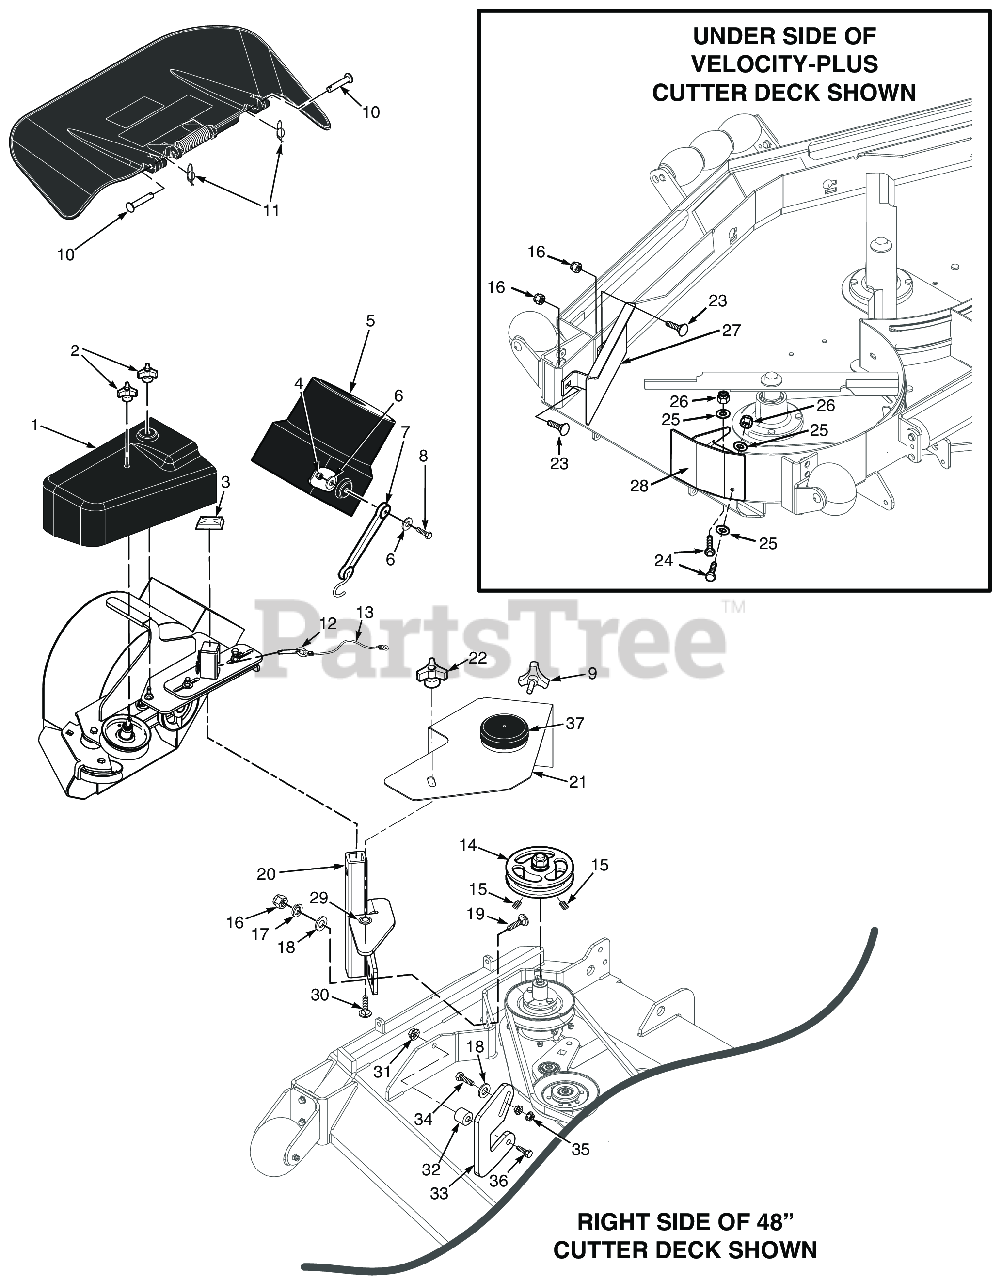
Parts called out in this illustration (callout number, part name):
1	Belt Cover, 48"
1	Belt Cover, 52"
2	Wing Nut, 3/8-16 (Small) Top side
3	Cap, Square Vinyl
4	HEX, NUT, ELASTIC STOP LOCK, 1/4-20
5	Adapter, Blower GC-STC,
6	Flatwasher, 1/4" (.312 x .750 x .065")
7	Rubber Strap 7-3/4"
8	SERR. FLG. HEX HEAD CAPSCREW, 5/16-18 X 3/4
9	Knob, w/stud 3/8-16 x 1-1/4"
10	Clevis Pin, 5/16 x 1-1/2"
11	Pin, Rue Cotter 5/16 Dia.
12	Pin, Ring 1/2 x 2-1/4"
13	Lanyard, Deck Height Pin
14	Pulley, 4.0" Dia. - 1.125" Bore, (STT-52 & STTII-52)
15	Setscrew, Hex Socket Knurl Cup Pt. 5/16 - 18 (nylock)
16	HEX NUT, ELASTIC STOP LOCK, 3/8-16
17	Lockwasher, 3/8" Spring, Kawasaki FX / FS
18	Flatwasher, 3/8" Special (.391 x .938 x .105)
19	SHORT SQ. NECK CARRIAGE BOLT, 3/8-16 X 1-1/4"
20	Mounting Post Weldment, Blower, (61")
21	Belt Cover Assembly, w/Cap - 48"
21	Belt Cover Assembly, w/Cap - 52"
22	Wing Nut, 3/8-16 (Small) Top side
23	Carriage Bolt, 3/8-16 x 1.0"
24	Bolt, Heax Head 5/16-18 x 1" (48V / 52V)
25	Flatwasher, 5/16-.375 x .875 x .083 (35BV & 37BV-EFI)
26	HEX NUT, ELASTIC STOP LOCK, 5/16-18
27	Baffle Weldment, 52V Deck
28	Baffle, Turbo 48" Deck
28	Baffle, Turbo 52" Deck
29	Nut, Push-On - 3/8" Dia.
30	Carriage Bolt, 3/8-16 x 1-1/4"
31	NUT, 3/8-16 SERRATED FLANGE HEX HEAD
32	Spacer (STCII48 & SCZ48)
33	Bracket (STCII48 & SCZ48)
34	Bolt, Hex Head 3/8-16 x 1-1/2" Grade 8 Black
35	NUT, 3/8-16 SERRATED FLANGE HEX HEAD
36	Bolt, Hex Head 3/8-16 x 1-3/4" (Kohler EFI)
